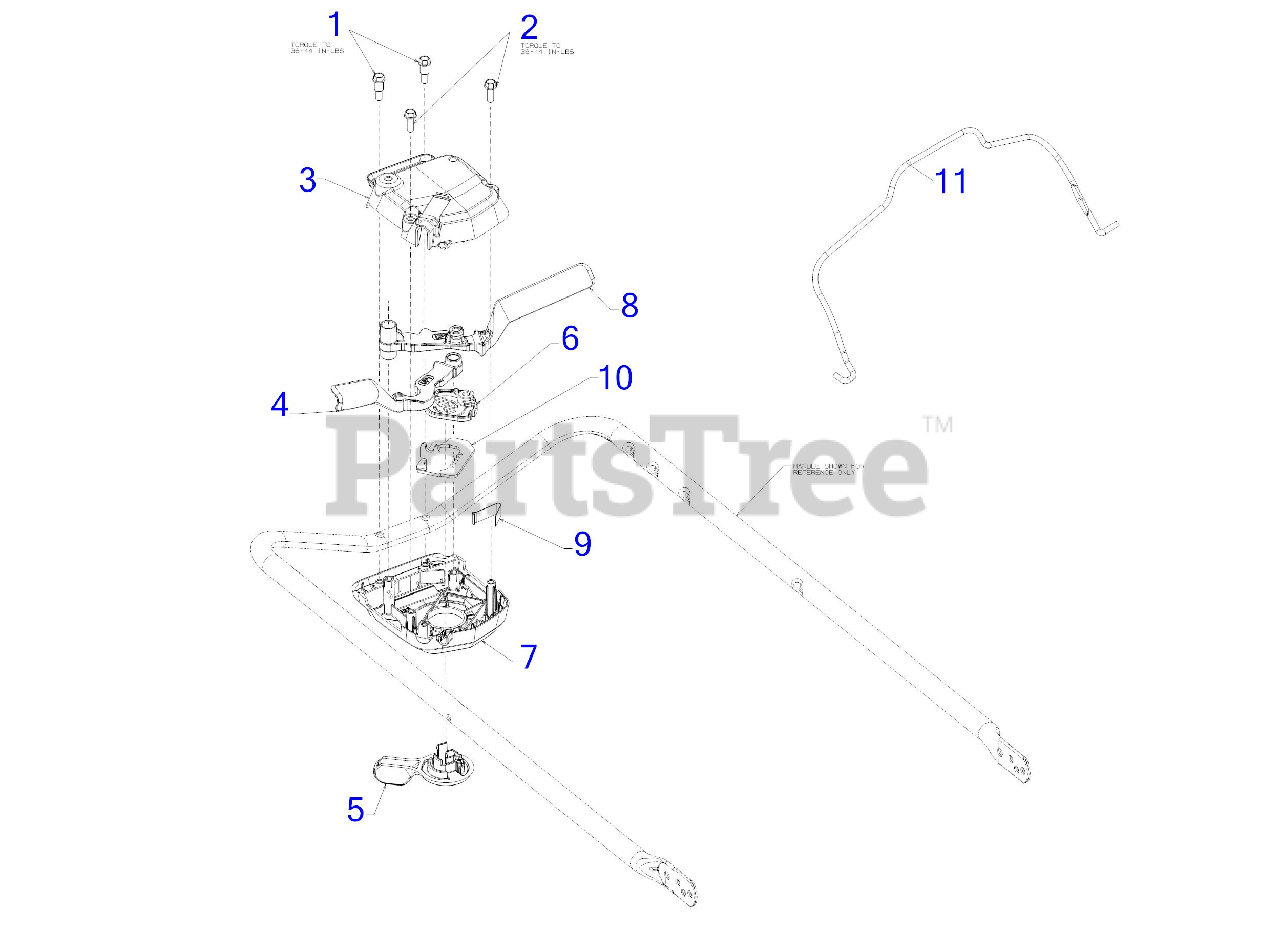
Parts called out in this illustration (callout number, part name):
1	SHOULDER SCREW 1/4-15 x .970
2	SCREW 1/4-15 x .750
3	LOWER CONTROL HOUSING
4	CONTROL LEVER (LH)
5	SPEED SELECT LEVER
6	CABLE SPEED ADJUST ACTUATOR
7	UPPER CONTROL HOUSING
8	CONTROL LEVER (RH)
9	SHIFT SPRING
10	RACK PLATE
